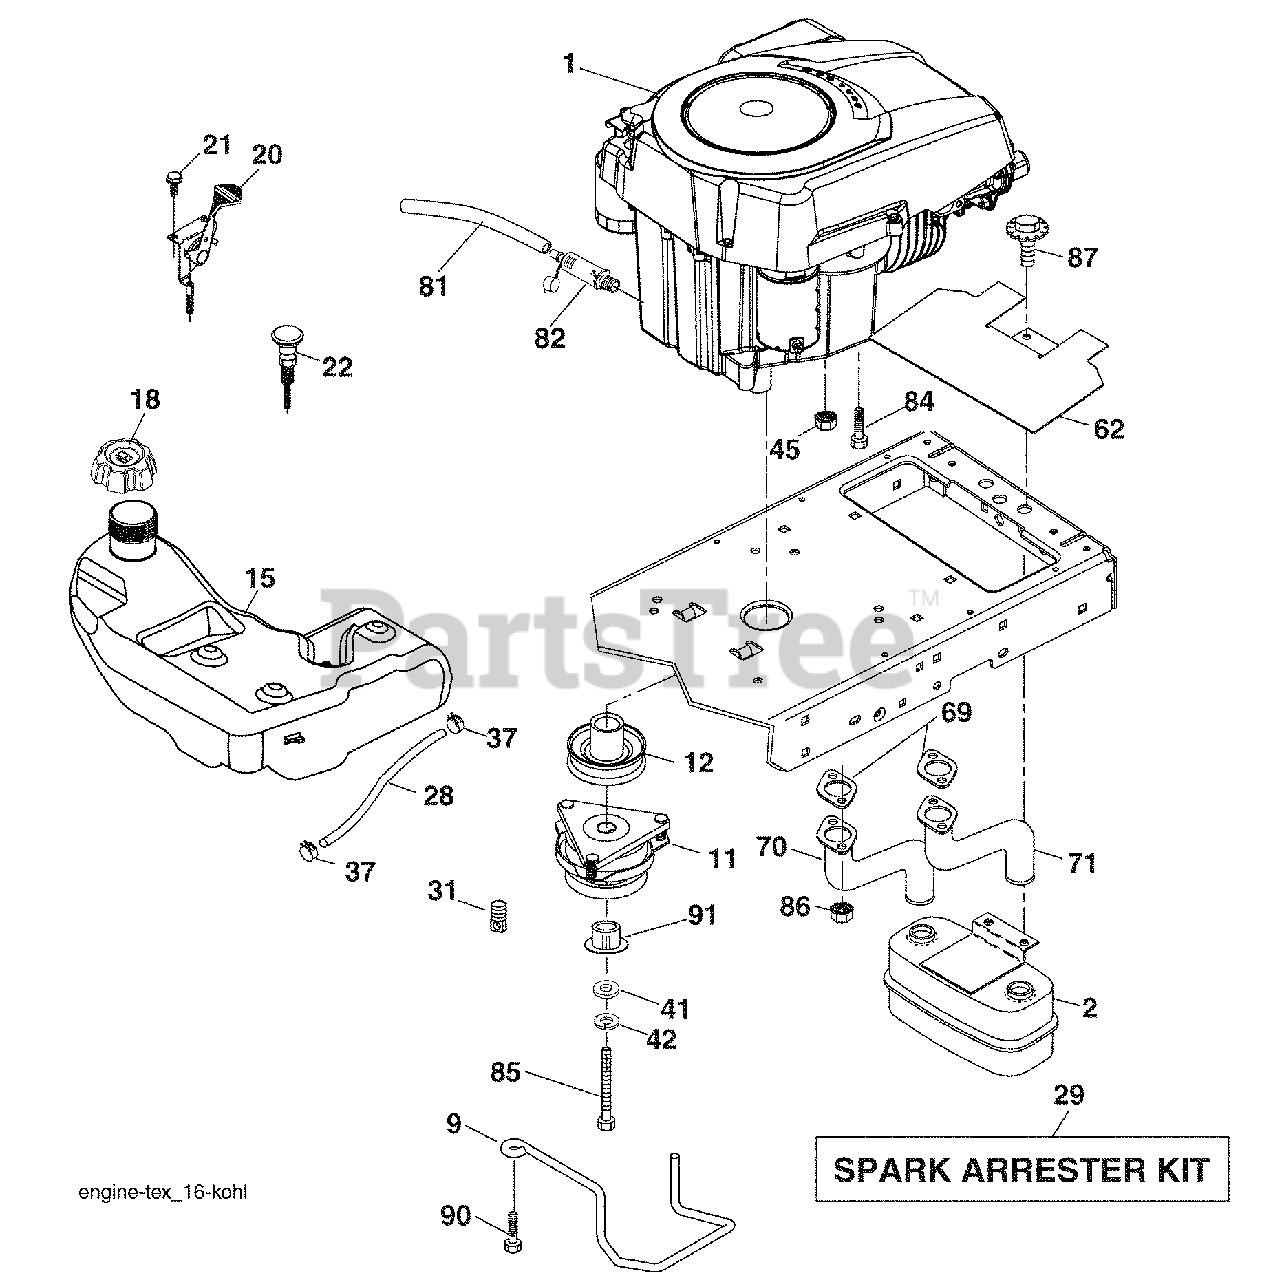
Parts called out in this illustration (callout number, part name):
9	Keeper Belt Engine
11	Clutch Electric
12	Pulley Engine
15	Tank Fuel 4.0
18	Cap Asm
20	Control Throttle
21	Screw 10 x 3/4 Single Lead Hex
22	Control Choke
28	Fuel Line
29	Spark Arrester Kit
31	Clip Push-In
37	Clamp Hose
41	Washer 1-1/2 OD x 15/32 ID x .250
42	Washer Lock 7/16
45	Nut Keps Hex 1/4-20 unc
62	Shield Heat Muffl er
70	Tube Exhaust LH
71	Tube Exhaust RH
81	Tube Drain Oil Easy
82	Plug Drain Oil
84	Screw 3/8-16 x 1
85	Bolt Hex 7/16-20 x 3.75 Gr. 5
86	Nut Hex M8-1.25
87	Bolt 5/16-18 unc x 1 w/Sems
90	Screw 3/8-16 x 1
